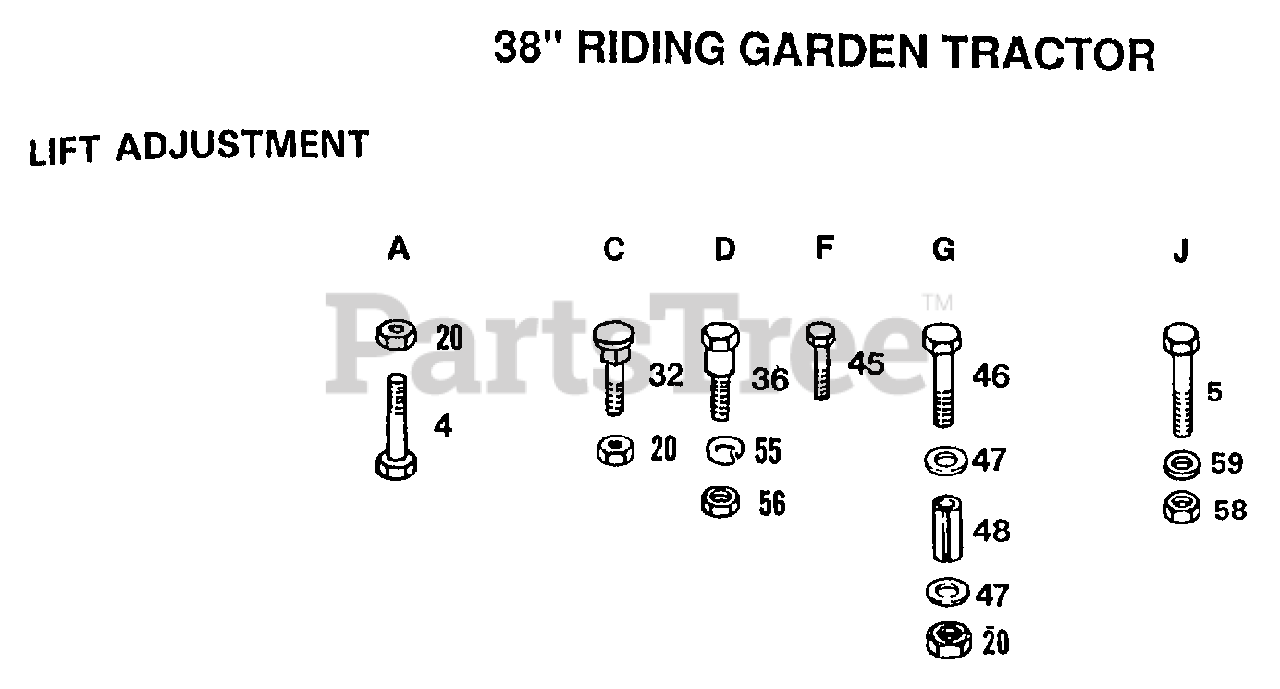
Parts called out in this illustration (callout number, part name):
5	WASHER M
32	PULLEY IDLER
36	SUPPORT PLATE LT
45	SPRING.RETAINER
47	ROCKSHAFT T
55	"BRKT,SUSP REAR LH"
56	BRAKE LT
58	ROD BRAKE LT
59	"BRK,BRAKE,PVT LT"
